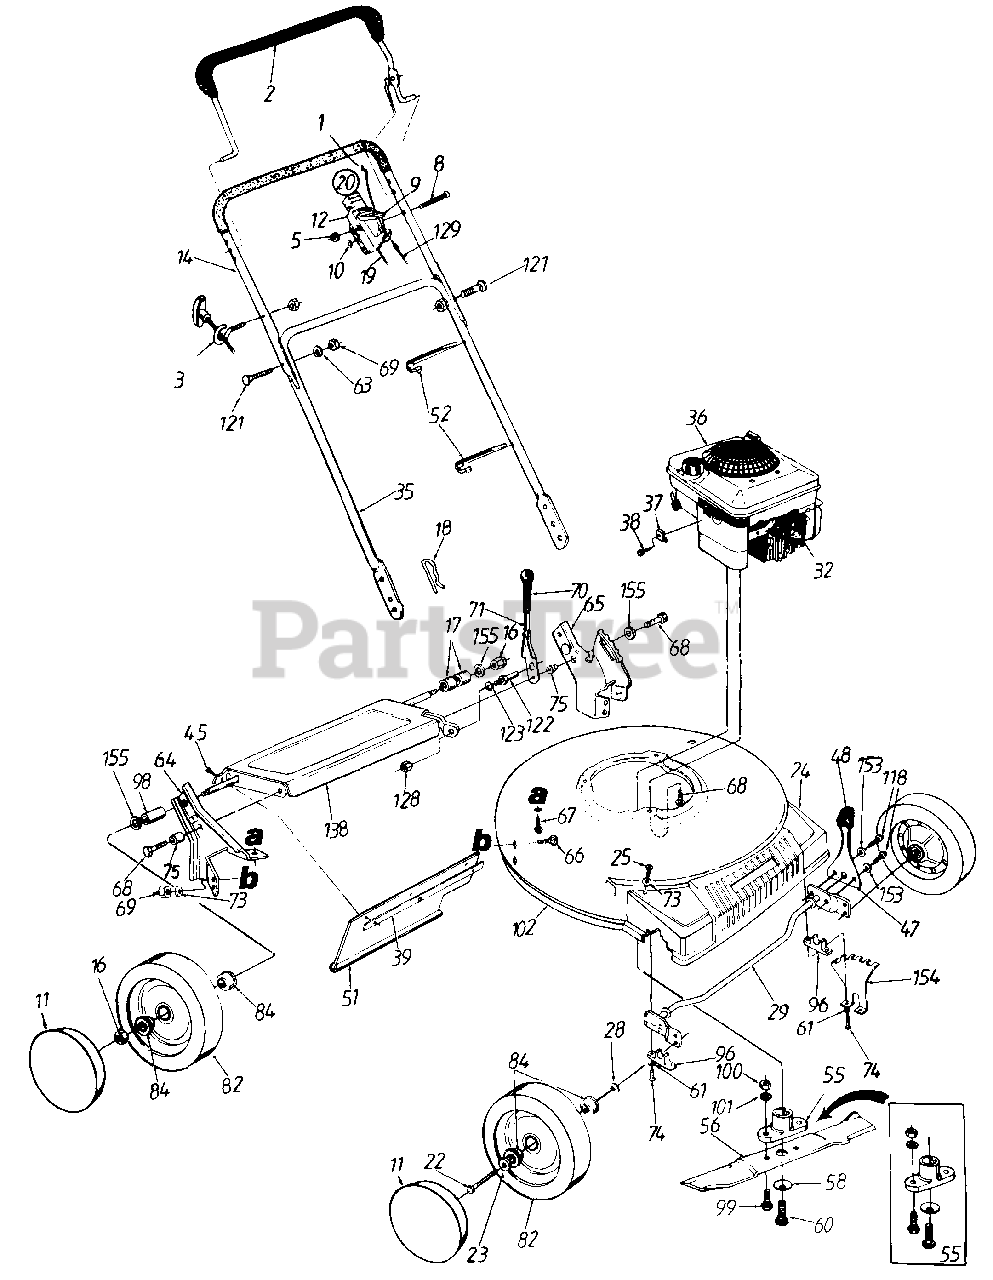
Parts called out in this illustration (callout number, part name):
1	Grip
2	Control Handle Ass'y.
3	Rope Guide Bolt
5	Hex L-Nut 1/4-20 Thd.
8	Oval C-Sunk Mach. Scr.
9	Throttle Lever
10	Spr. Wash. .66" I.D.
11	Hub Cap
12	Throttle Body
17	Spacer .526" I.D. x .64" Lg.
18	Internal Cotter Pin 5/16" Dia.
19	Throttle Control Wire - 55" Lg.
20	Throttle Box Comp.
22	Front Axle Bolt
23	Wave Wash. .53" I.D. x .78"
24	Plastic Front End
25	Truss B-Tap Scr. 5/16 x .75" Lg.
28	Bell-Wash. .38" I.D. x .88"
35	Lower Handle
36	Engine
37	Cable Clamp
38	Hex Wash. Hd. Scr. #10-32 x .62" Lg.
39	Retaining Strip
45	Hex AB-Tap Scr. #10-32 x .62" Lg.
47	Spring Lever
48	Knob
51	Rear Flap 3.75" x 17.30" Lg.
52	Cable Tie
55	Blade Adapter Kit
56	21" Mulching Blade
58	Bell-Wash. .47" I.D. x 1.14" O.D.
60	Hex Bolt 7/16-20 x 2.5" Lg.
61	L-Wash. 1/4" I.D.
63	L-Wash. 5/16" I.D.
64	R.H. Handle Wheel Brkt. Ass'y
65	L.H. Handle Wheel Brkt. Ass'y
66	Carriage Bolt 5/16-18 x .62"
67	Hex B-Tap Scr. 5/16-18
68	Hex TT-Tap Scr. 3/8-16
69	Hex Nut 5/16-18 Thd.
71	Height Adj. Lever
73	Bell-Wash. 5/16" I.D.
74	Hex Wash. Hd. B-Tap Scr. 1/4-20 x 1" Lg.
75	Shld. Spacer .5" Dia.
82	Wheel Ass'y. Comp.
84	Ball Bearing 1/2" I.D.
96	Block Bushing
98	Sleeve .526" I.D.
99	Hex Bolt 3/8-24 x 1.0" Lg.
100	Hex Nut 3/8-24 Thd.
101	L-Wash. 3/8" I.D.
121	Curved Carr. Bolt 5/16-18 x 1.38" Lg.
122	Shld. Pin 1.43" Lg.
123	L-Wash. 3/8" I.D.
128	Hex Jam Nut 3/8-24 Thd.
129	Control Cable - 39"
138	Rear Axle Ass'y.
153	External L-Wash. 1/4" I.D.
154	Height Adj. Brkt.
155	Fl-Wash. .385" I.D. x .87" O.D.
